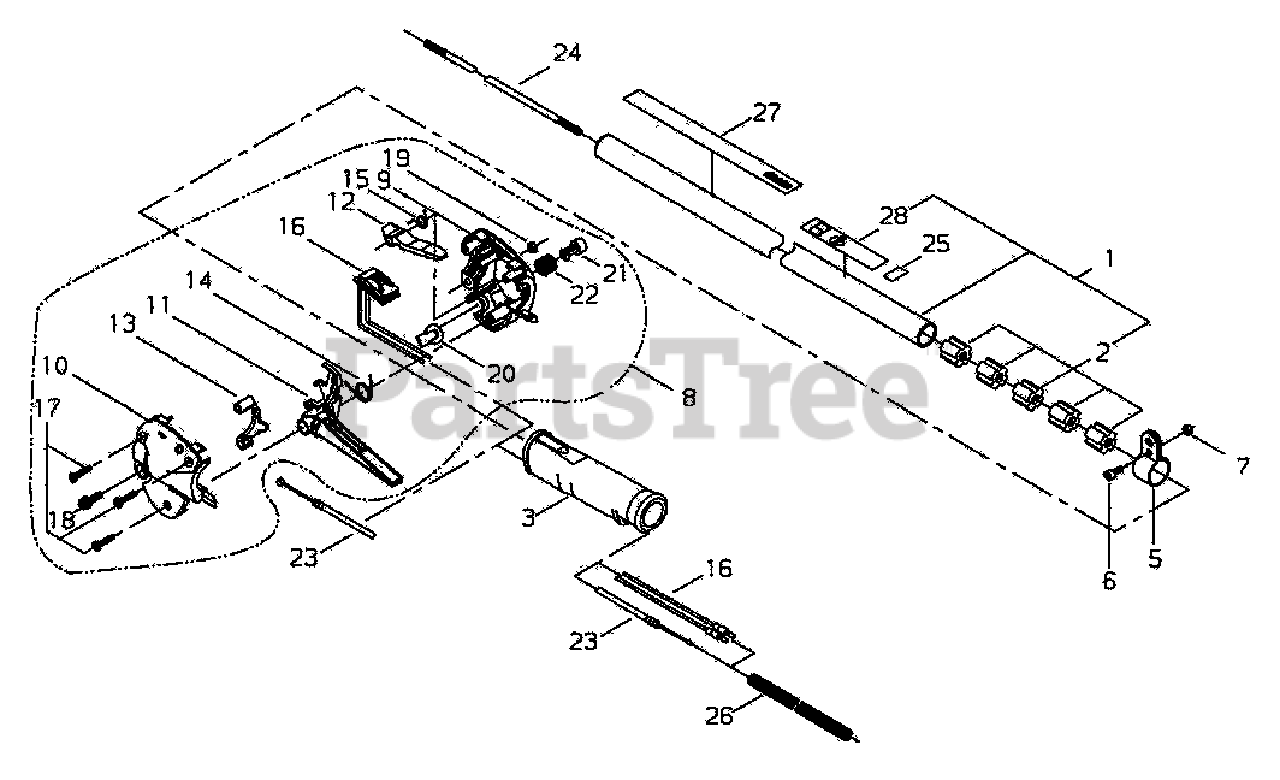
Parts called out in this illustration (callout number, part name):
1	MAIN PIPE ASSY
2	BUSHING
3	GRIP
5	HANGER
6	BOLT 5×12
7	NUT M5
8	THROTTLE CONTROL ASSY
9	CONTROL HANDLE - RIGHT
10	CONTROL HANDLE - LEFT
11	TRIGGER, THROTTLE
12	LEVER, THROTTLE LOCKOUT
13	LOCKOUT, THROTTLE
14	SPRING, THROTTLE RETURN
15	SPRING, THROTTLE LOCKOUT
16	SWITCH, ON-OFF
17	SCREW, TAPPING M4×20
18	SCREW M5×20
19	NUT M5
20	PLUG
21	BUTTON, THROTTLE LOCK
22	SPRING, COMPRESSION
23	CABLE, THROTTLE
24	MAINSHAFT
25	LABEL, HANDLE
26	TUBE, PLASTIC PROTECTIVE
27	LABEL, SHINDAIWA PROFESSIONAL
28	LABEL, CAUTION (BLADE CAPABLE)
